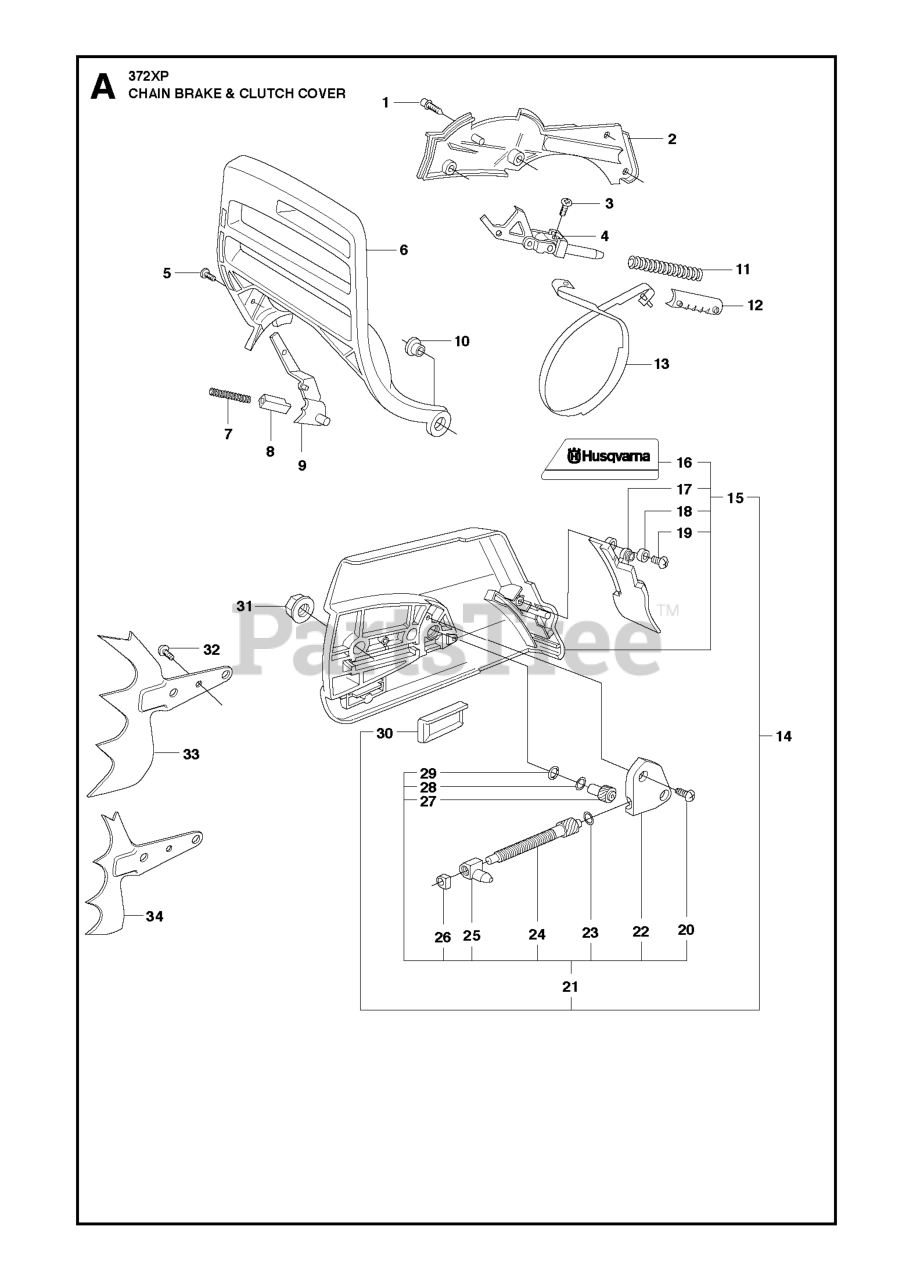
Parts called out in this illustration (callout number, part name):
1	SCREW ITXSCFM M5X12 T27 12.9
3	SCREW CITXPANT
5	SCREW ITXSCM M4X12 T27 12.9 T
7	LOCK SPRING
9	BRAKE LEVER
11	BRAKE SPRING
13	BRAKE BAND
14	CHAIN BRAKE COVER
15	CHAIN BRAKE COVER
19	SCREW CITXPANT
20	SCREW CITXPANT
21	KIT-CHAIN TENSIONER
24	WORM SCREW / ADJUSTER
27	WORM WHEEL
30	CHAIN GUIDE
31	NUT M8 FLANGE
32	SCREW CITXPANT
33	FELLING DOG
34	SPIKE OUTER
